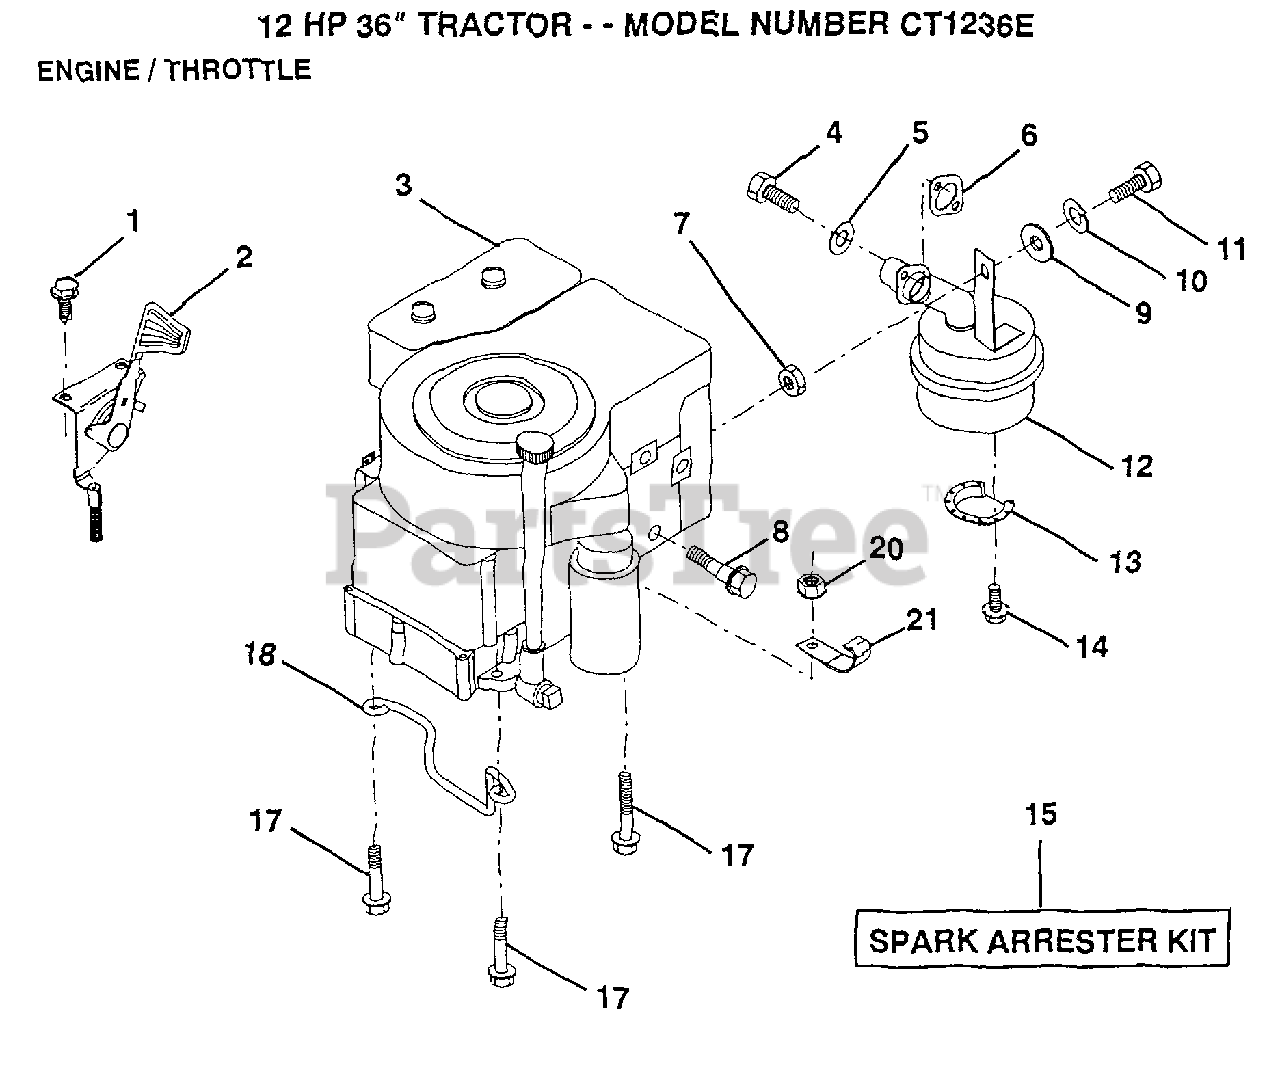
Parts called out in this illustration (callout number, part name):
1	SCREW
2	THROTTLE CONTROL
4	SCREW
5	LOCKWASHER
7	NUT.HEX.5/16-18
8	BOLT T
10	LOCKWASHER
12	MUFFLER
13	DEFLECTOR.222573
17	SCREW LT
18	"KEEPER,DR BELT GR"
20	NUT
21	CLIP T
